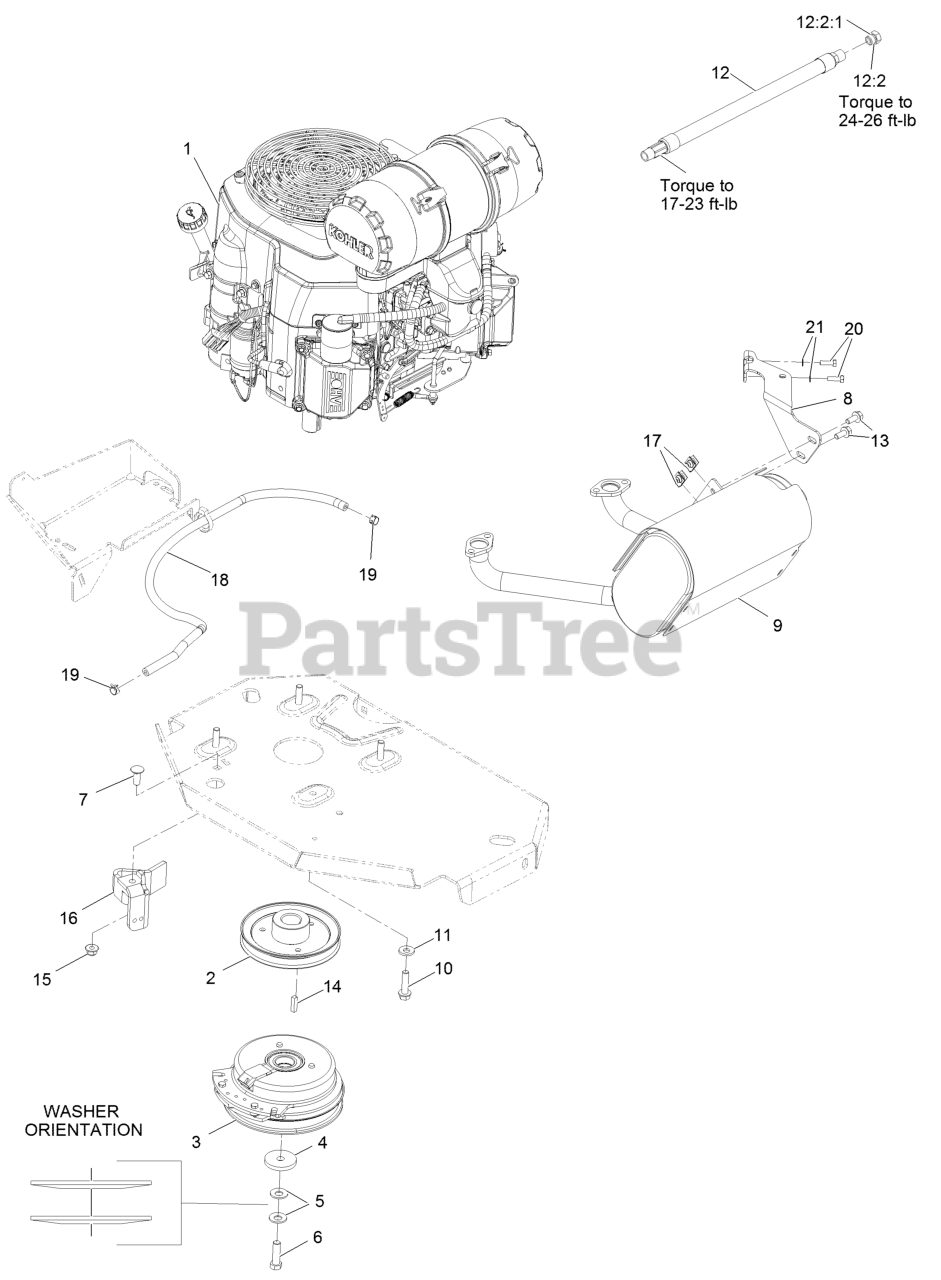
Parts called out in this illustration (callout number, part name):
1	Engine-Kohler
2	SHEAVE
3	CLUTCH KIT
4	WASHER-CLUTCH
5	WASHER-SPRING
6	SCREW-HH 7/16-20 X 1 1/2 W/LOCTITE
7	SCREW-CARR
8	MUFFLER BRACKET KIT
10	SCREW-HWH
11	WASHER-BELLEVILLE
12	OIL DRAIN HOSE ASM
12:2	PLUG-HH
12:2:1	O-RING
13	SCREW-HHF
15	NUT-HF, NI
16	CLUTCH-ANCHOR
18	HOSE-FUEL
19	CLAMP-HOSE
20	SCREW-HH M6-1 X 20Mm W/Patch
21	Washer-Spring Disc 1/4
